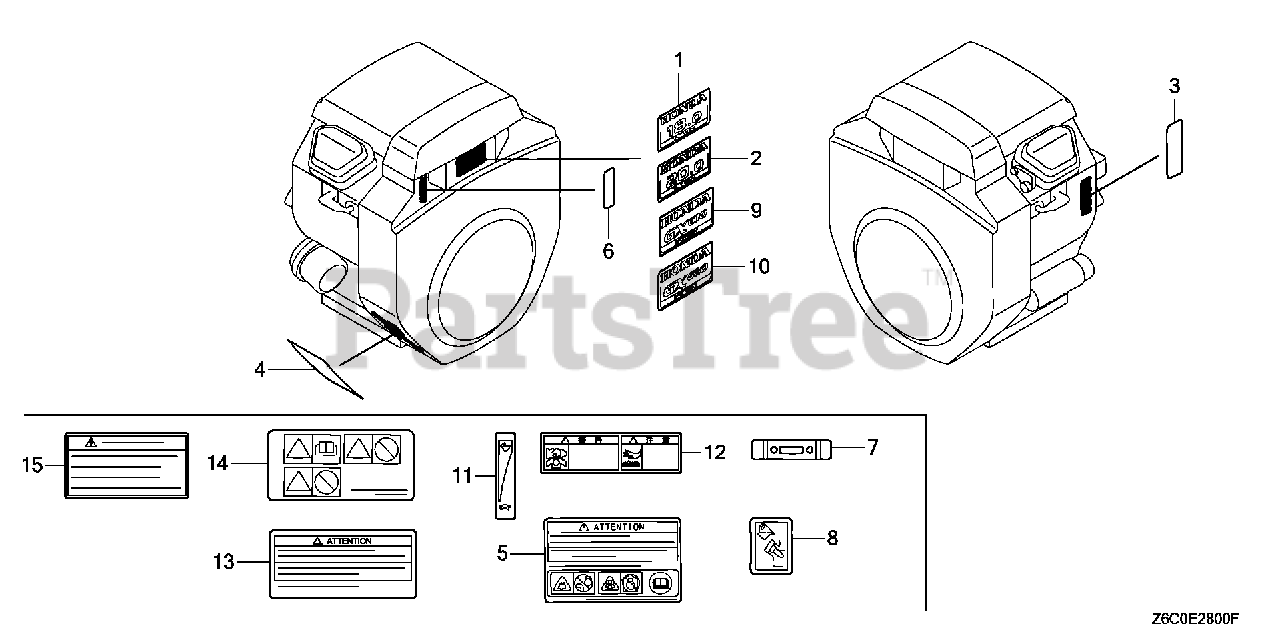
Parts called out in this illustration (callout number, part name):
1	EMBLEM (GX610)
3	LABEL, SPECIFICATION (GX610)
4	MARK, OPERATOR CAUTION (PICTOGRAPH)(MADE IN JAPAN)
5	MARK, OPERATOR CAUTION (ENGLISH)(MADE IN JAPAN)
5	MARK, OPERATOR CAUTION (FRENCH)(MADE IN JAPAN)
6	MARK, THROTTLE INDICATION
9	EMBLEM (GX610)
13	MARK, OPERATOR CAUTION (ENGLISH)(MADE IN JAPAN)
13	MARK, OPERATOR CAUTION (FRENCH)(MADE IN JAPAN)
14	MARK, OPERATOR CAUTION (PICTOGRAPH)
